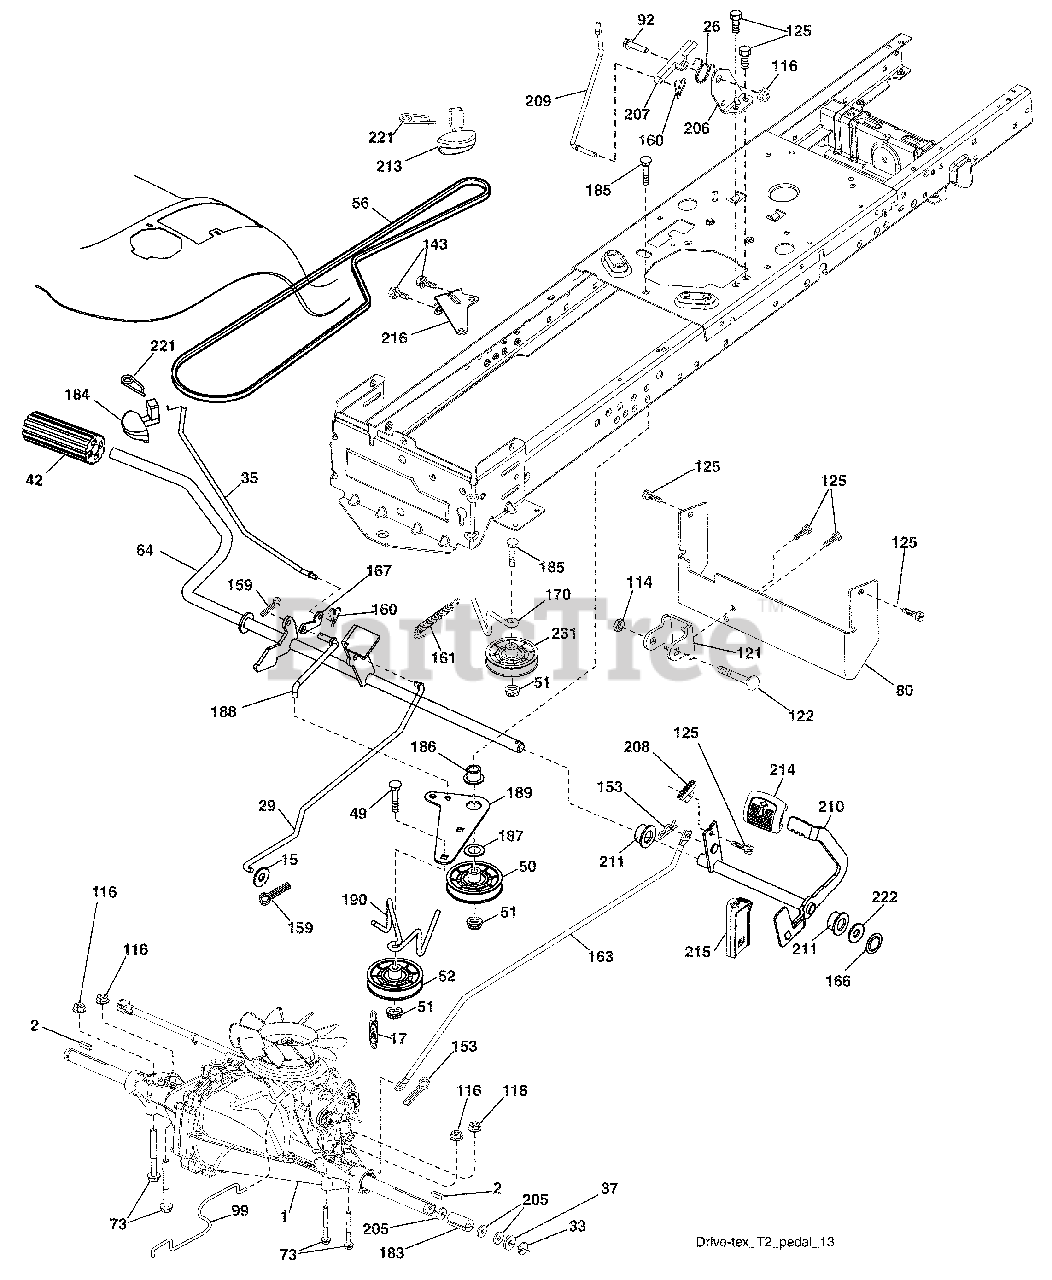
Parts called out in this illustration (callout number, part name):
15	Washer 13/32 x 13/16 x 16 Ga.
17	Spring, Brake
26	Spring Return Cruise
29	Rod, Brake
35	Rod, Brake, Park
37	Washer 25/32 x 1-1/4 x 16 Ga.
42	Cover, Foot Pedal
50	Pulley Idler Flat
51	Lock Nut 3/8-16
52	Idler V-Groove 910" Offset
56	V-Belt, Drive
64	Shaft Asm. Pedal Brake Control
73	Bolt 5/16-18 Gr. 5
80	Strap Torque
92	Bolt Fin Hex 5/16-18 unc x 1.25
99	Rod Asm Bypass Spring
114	Nut Lock 5/16-18 unc
116	Nut Lock Hex Flange 5/16-18
121	Bracket Strap Torque
122	Bolt 5/16-18 x 2.50
125	Screw 5/16-18 x 3/4
143	Screw THDROL 5/16-18 x 1/2
153	Retainer Spring
159	Pin Cotter 1/8 x 3/4
160	Retainer Clip
161	Spring, Return, Clutch
163	Rod Pedal Control
166	Nut Push .625
167	Latch Brake Parking
170	Keeper Belt Centerspan
183	Spacer Axle
184	Handle Parking Brake
186	Spacer Retainer
187	Washer
188	Link Clutch Ground Drive
189	Bellcrank Ground Drive
190	Keeper Bellcrank Ground Drive
205	Washer 25/32 x 1-5/8 x 16 Ga.
206	Bracket Mount Latch Cruise
207	Latch Control Cruise
208	Gear Sector Control Cruise
209	Rod Control Cruise
210	Rocker Asm. Pedal Control
211	Bearing Nylon
213	Knob Control Cruise
214	Pad Pedal Forward
215	Pad Pedal Reverse
216	Braket Pulley Idler
221	Retainer Spring Clip Handle
222	Washer 21/32 x 1-1/4 10 Ga.
231	Idler V-Groove 1.688
